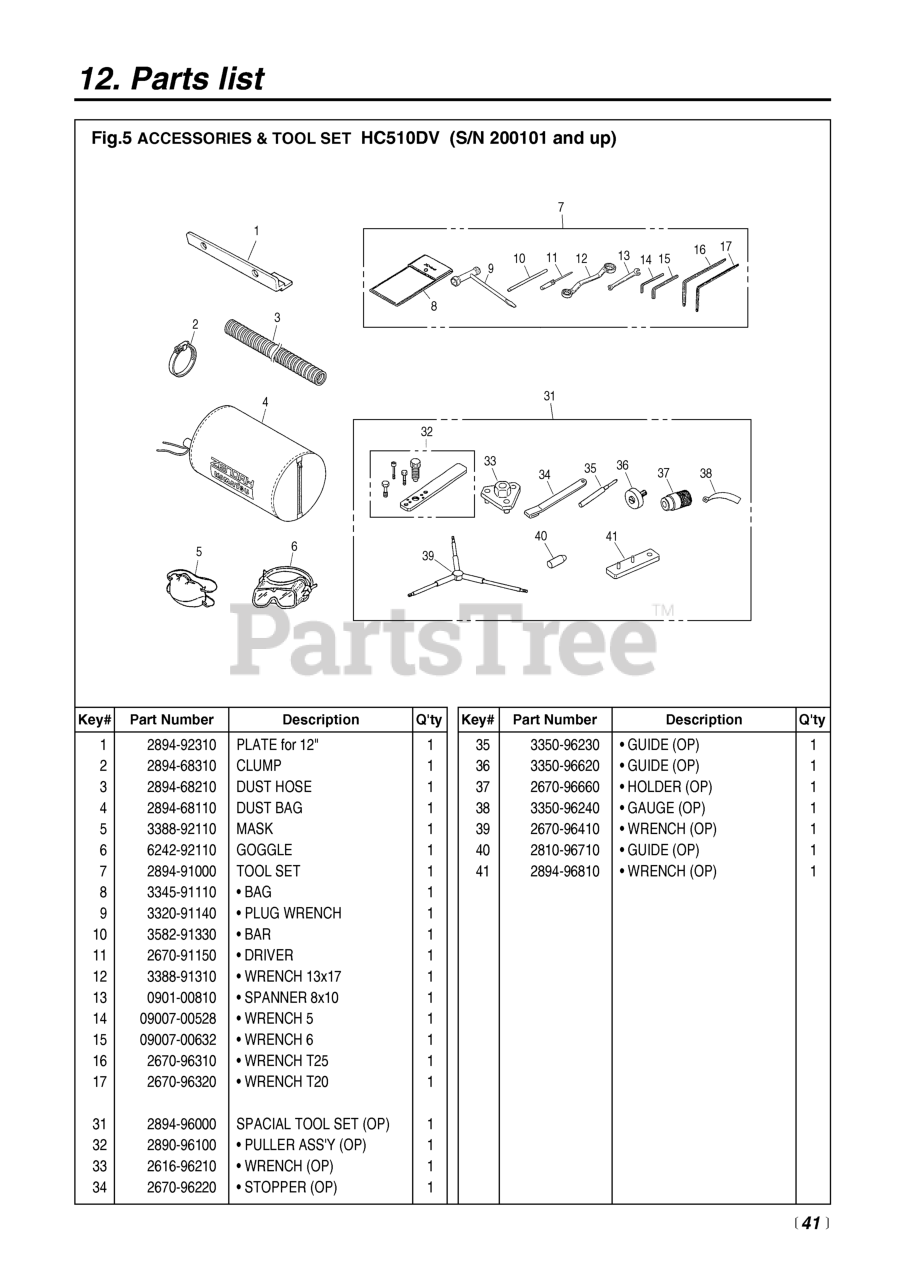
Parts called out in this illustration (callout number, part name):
1	PLATE FOR 12
3	DUST HOSE
4	DUST BAG
7	TOOL SET
9	WRENCH, PLUG
11	SCREWDRIVER
14	WRENCH (TOOL)
16	WRENCH (TOOL)
17	WRENCH (TOOL)
31	TOOL SET
32	PULLER ASSY
33	WRENCH, CLUTCH (TOOL)
34	STOPPER (TOOL)
35	GUIDE (TOOL)
36	GUIDE (TOOL)
37	HOLDER (TOOL)
38	GUAGE, AIR GAP (TOOL)
40	GUIDE (TOOL)
